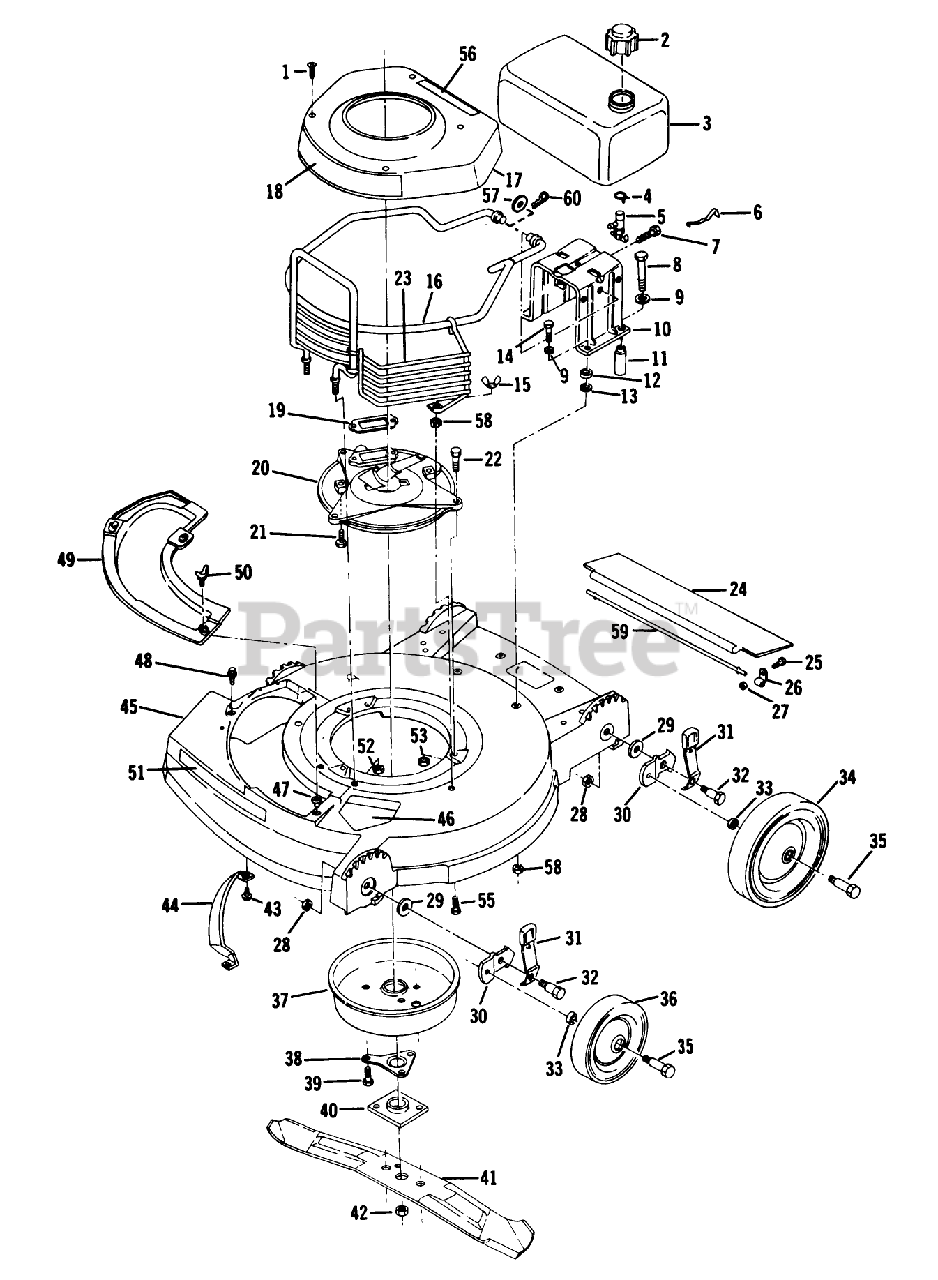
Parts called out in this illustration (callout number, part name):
1	SCREW - SELF TAPPING
2	FUEL CAP & INSERT
4	CLAMP - HOSE S
5	VALVE&SCREEN SM
6	SPRING
7	SCREW S
9	WASHER
13	WASHER
14	BOLT PIONEER
21	SCREW V
22	SCREW-HH
24	T/SHIELD GEAUGA
26	CLAMP ROD KMC
27	LOCKNUT E
29	WASHER
32	BOLT
33	WASHER WROUGHT
34	WHL & TIRE AY
35	BOLT-SHOULDER
36	WHEEL & TIRE ASSY
37	MUFFLER COVER F
38	SUPPORT F
39	SCREW
40	PLATE AND COLLAR ASM
42	NUT-BLADE
44	BAR-TOE
50	WING SCREW LAWRE
52	NUT-LOCK F
53	NUT-LOCK F
55	Screw
57	WASHER SPRING LAR
58	LOCKNUT E
59	ROD 21" ADVANCE
60	HAIR PIN
